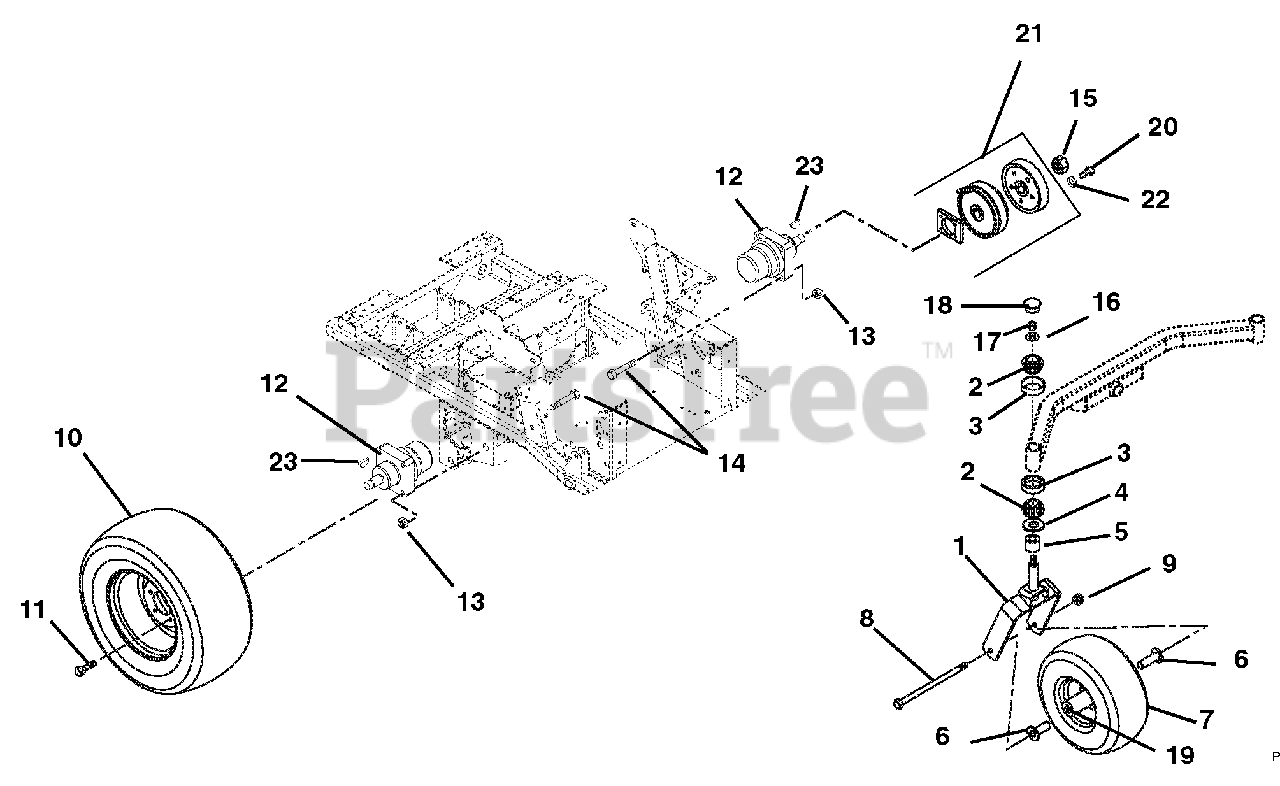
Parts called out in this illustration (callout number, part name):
1	Fork, Front
2	Bearing, Cone w/ Grease
3	Bearing, Cup 1.980 x .420
4	Bearing Seal 1.5 x 2 x .18
5	Spacer, PM, 1.03 I.D. x 1.5 O.D. x .375
6	Spacer, Wheel
7	Wheel/Tire Assembly 15 x 6-6
8	Bolt, Hex .50-13 x 9.00 Grade 5
9	Nut, Locking Center .50-13
10	Tire/Wheel Assembly 24 x 11.5-12
11	Bolt, Lug .50-20 x 1.38
12	Hydraulic Wheel Motor (Includes item 15)
13	Nut, Locking Top Flange .50-13
14	Bolt, Wheel Motor .50-13 x 2.75
15	Nut , Lock Jam Patch (Included with 12)
16	Washer, Flat Steel 812 x 1.50 x .135
17	Nut, Jam Center-Lock .75-16
18	Cap, Dust
19	Bearing, 25mm I.D. x 52mm OD x 15mm
20	Bolt, Hex .31-18 x 1.5 Grade 8
21	Kit, Parking Brake Service
22	Washer, Locking .31 x 1.00
23	Key, Wodruff .31 x 1.00 (For Service Only)
